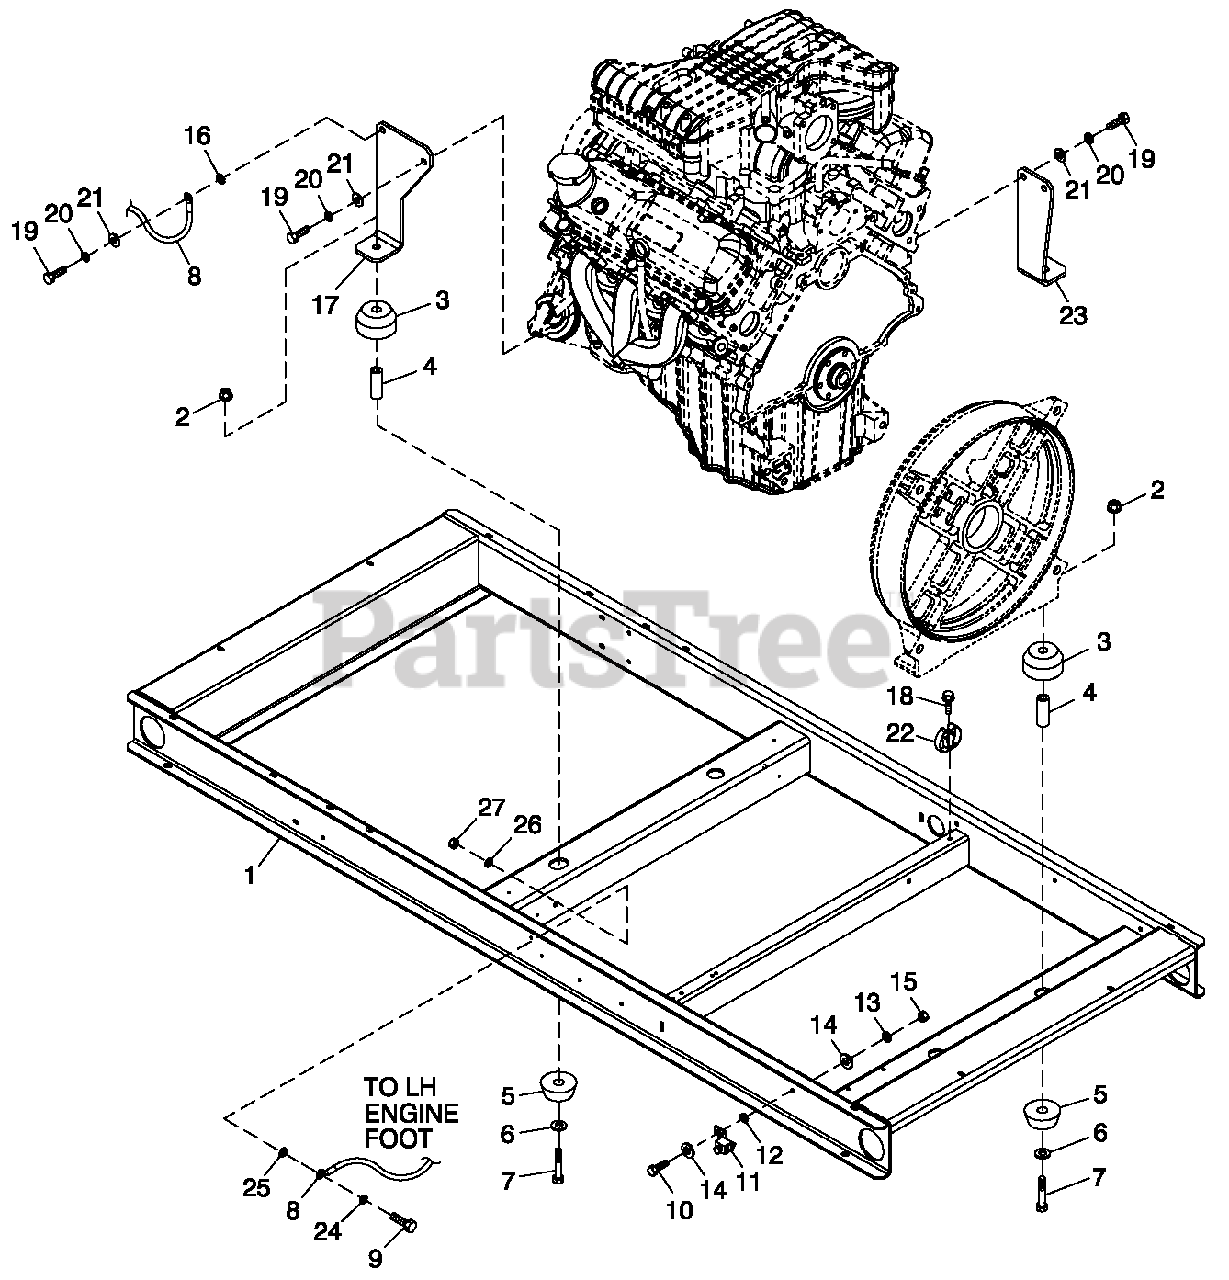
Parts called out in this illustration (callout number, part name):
1	WELDMENT BASEFRAME 4.2L G3
2	NUT FLANGED HEX M12-1.75
3	DAMPENER VIBRATION 40 BLUE
4	SPACER .49 X .62 X 1.87 PWDR/ZNC
5	DAMPENER VIBRATION
6	WASHER FLAT M12
7	SCREW HHC M12-1.75 X 80 G8.8
8	ASSY WIRE 14.00"
9	SCREW HHC M8-1.25X30 G8.8
10	SCREW HHC M6-1.0X 16 G8.8
11	LUG SLDLSS #2-#8X 17/64 CU
12	WASHER SHAKEPROOFINT1/4
13	WASHER LOCK M6-1/4
14	WASHER FLAT M6-1/4 ZINC
15	NUT HEX M6 -1.0 G8YELCHR
16	WASHER SHAKEPROOF INT 3/8
17	ENGINE FOOT L/H 4.2L CPL
18	SCREW HHTT M4-0.7 X 8 BP
19	SCREW HHC M10-1.5 X 30 C10.9
20	WASHER LOCK 7/16
21	WASHER FLAT 3/8-M10 ZINC
22	SPRING CLIP HOLDER .37-.62
23	ENGINE FOOT R/H 4.2L CPL
24	WASHER LOCK M8-5/16
25	WASHER SHAKEPROOF INT 5/16
26	WASHER FLAT 5/16-M8 ZINC
27	NUT HEX M8-1.25 G8 CLEAR ZINC
